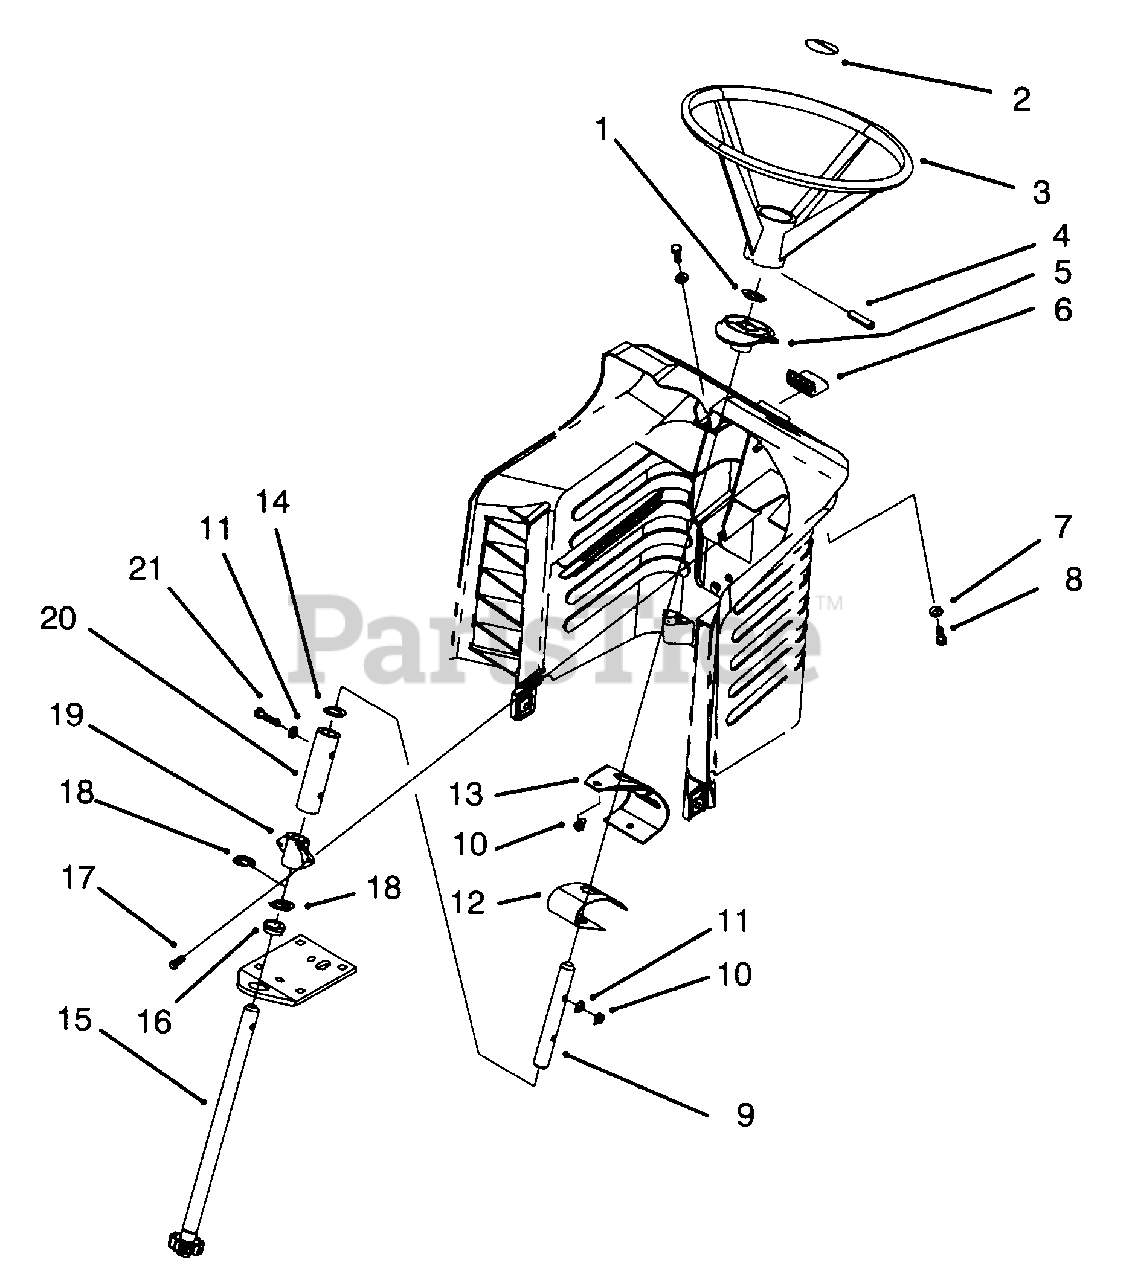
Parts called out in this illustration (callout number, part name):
1	Ring-Retaining
2	Insert-Steering Wheel
3	Wheel-Steering (Incl. Ref. #2)
5	Bushing-Sliding
6	Button-Release
7	Washer-Flat
8	Screw-Hex Hd. Cap
9	Shaft-Steering Upper
10	Nut-Lock
11	Washer-Curved
12	Bracket-Backup
13	Spring-Leaf
14	Washer-Thrust
15	Shaft-Steering Short
16	Bushing-Flange
17	Screw-Plastite
19	Bushing-Stationary
20	Coupling-Steering
21	Screw-Hex Hd. Cap
